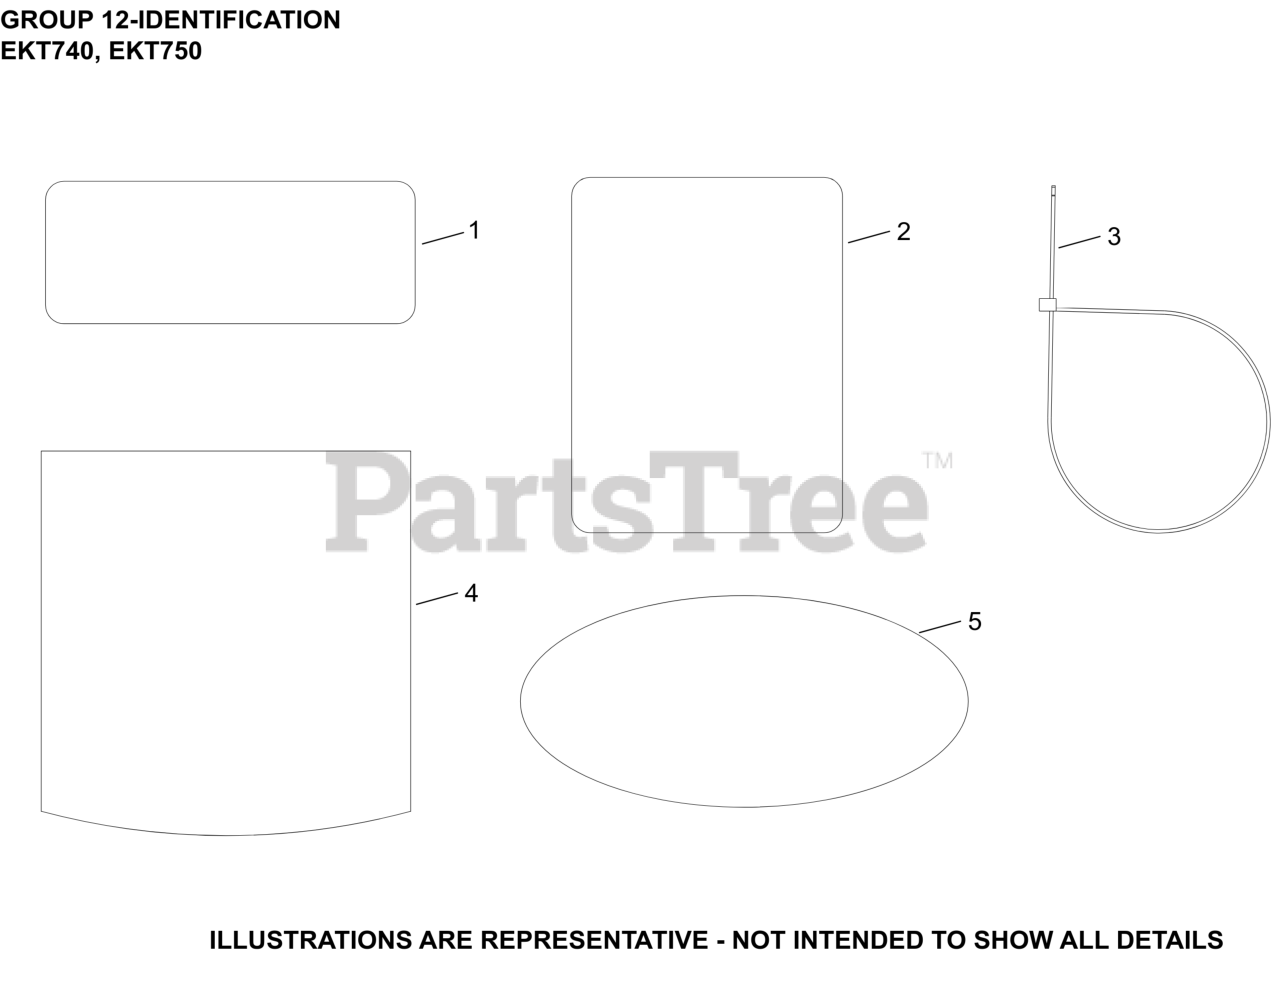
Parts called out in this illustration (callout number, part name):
1	LABEL, CANADIAN COMPLIANCE
2	LABEL, CLEAR LAMINATION
NI	DECAL, USA
NI	LABEL, 7500 SERIES EKT745 (26 HP)
